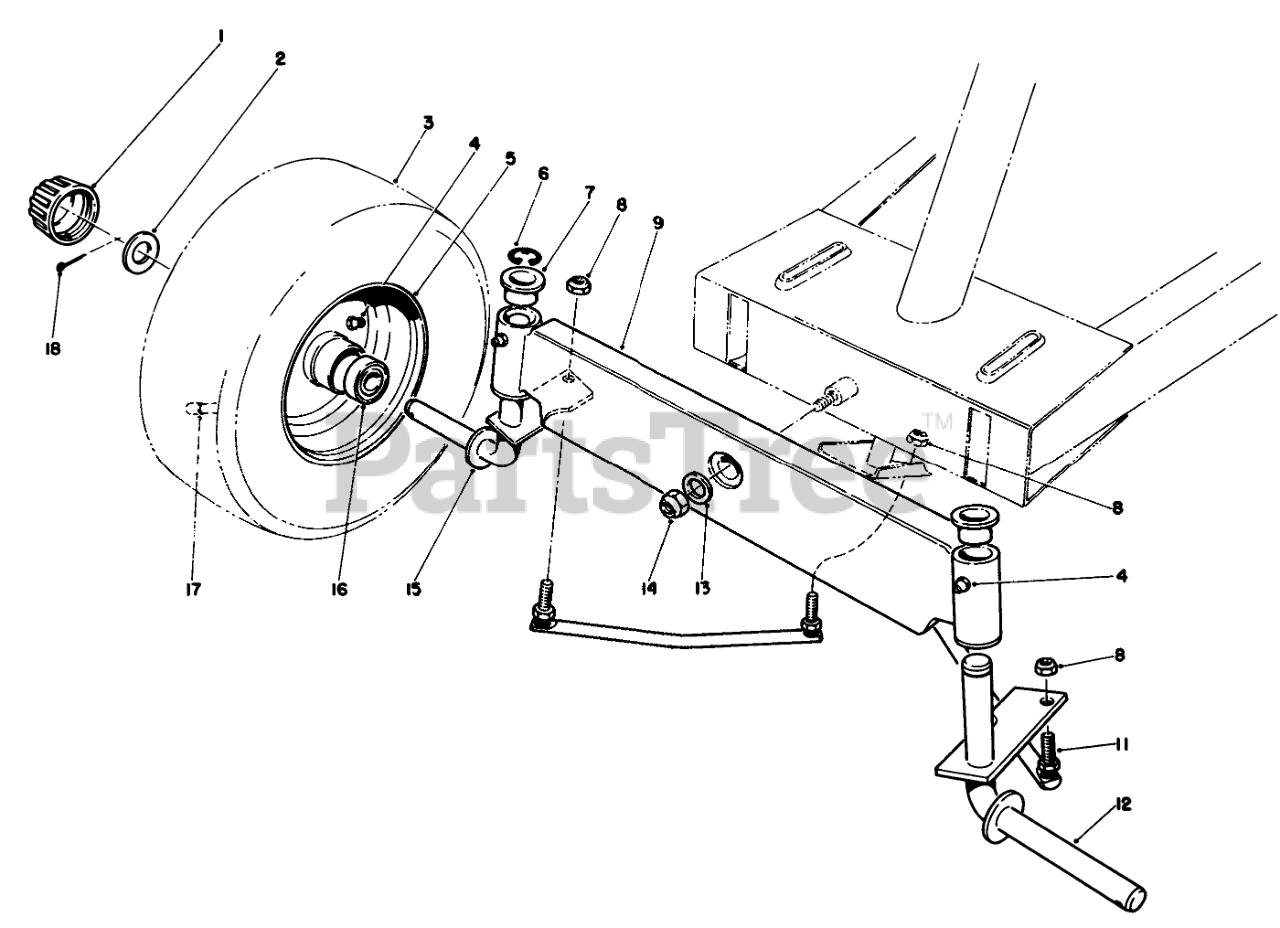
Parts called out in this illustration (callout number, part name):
1	CAP-HUB
2	WASHER-PLAIN
3	TIRE,PNEU.11X4.00X5
4	FITTING-GREASE
6	E-RING
7	BEARING-FLANGE
8	NUT-LOCK
9	Axle-Front
11	TIE ROD ASM
12	Spindle-L.H.
13	WASHER-FLAT
14	NUT-LOCK, NI
15	Spindle-R.H.
16	Bearing
17	STEM-VALVE
18	PIN-COTTER
